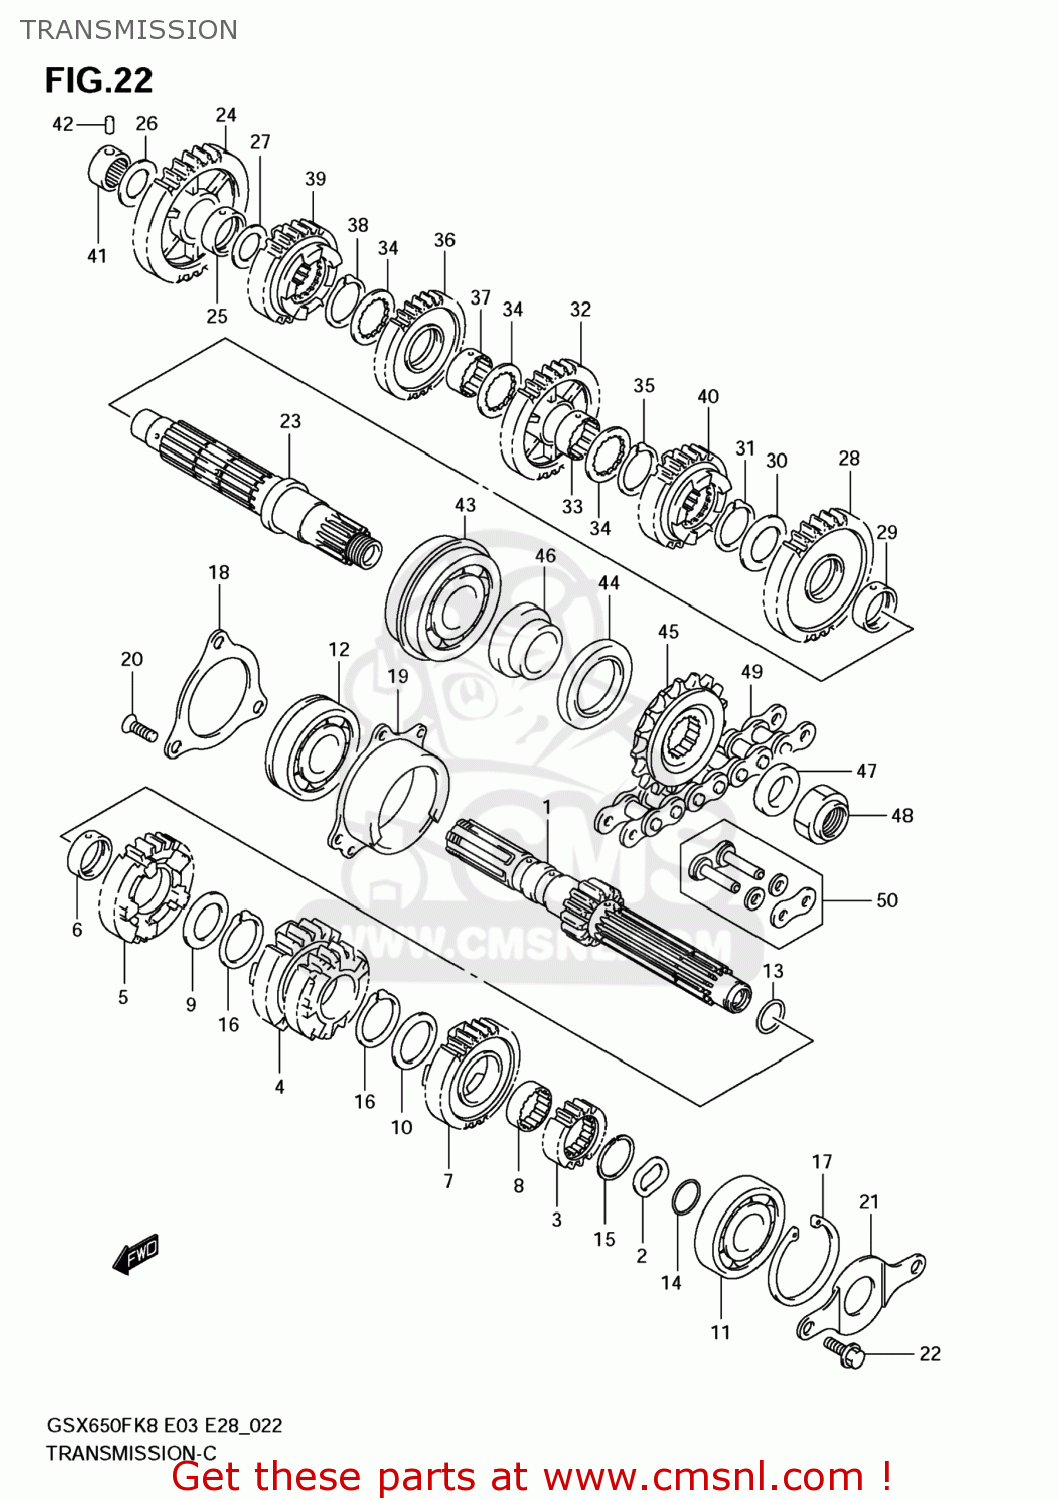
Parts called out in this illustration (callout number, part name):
1	SHAFT,COUNTER
2	WASHER,COUNTER SHAFT WAVE
3	GEAR,2ND DRIVE
4	GEAR,3RD & 4TH DRIVE
5	GEAR,5TH DRIVE
6	BUSH,5TH DRIVE GEAR
7	GEAR,6TH DRIVE(NT:28)
8	BUSH,6TH DRIVE GEAR
9	WASHER(27X36X1)
10	WASHER,LOCK
11	BEARING(20X52X15)
12	BEARING(25X62X17)
13	O RING(D:1.9,ID:16.6)
14	O RING(D:1,ID:19.5)
15	CIRCLIP
16	CIRCLIP
17	CIRCLIP
18	RETAINER,CNTR SHAFT BEARING,R
19	HOUSING,CNTR SHAFT BRG,R
20	SCREW(6X20)
21	RETAINER,CL PUSH ROD OIL SEAL
22	BOLT(6X12)
23	SHAFT,DRIVE
24	GEAR,1ST DRIVEN(NT:40)
25	BUSH
26	SHIM(20X34X1)
27	SHIM(22X34X1)
28	GEAR,2ND DRIVEN(NT:35)
29	BUSH,2ND DRIVEN GEAR
30	WASHER(27X36X1)
31	CIRCLIP
32	GEAR,3RD DRIVEN
33	BUSH
34	WASHER,3RD & 4TH DRIVEN
35	CIRCLIP
36	GEAR,4TH DRIVEN(NT:30)
37	BUSH
38	CIRCLIP
39	GEAR,5TH DRIVEN(NT:29)
40	GEAR,6TH DRIVEN
41	BEARING(20X34X13.5)
42	PIN(6X10)
43	BEARING(30X62X23.8)
44	SEAL,OIL(42X62X7)
45	SPROCKET,ENGINE(NT:15)
46	SPACER,ENGINE SPROCKET
47	SPACER,ENGINE SPROCKET NO.2
48	NUT
49	CHAIN ASSY,DRI
50	JOINT SET
